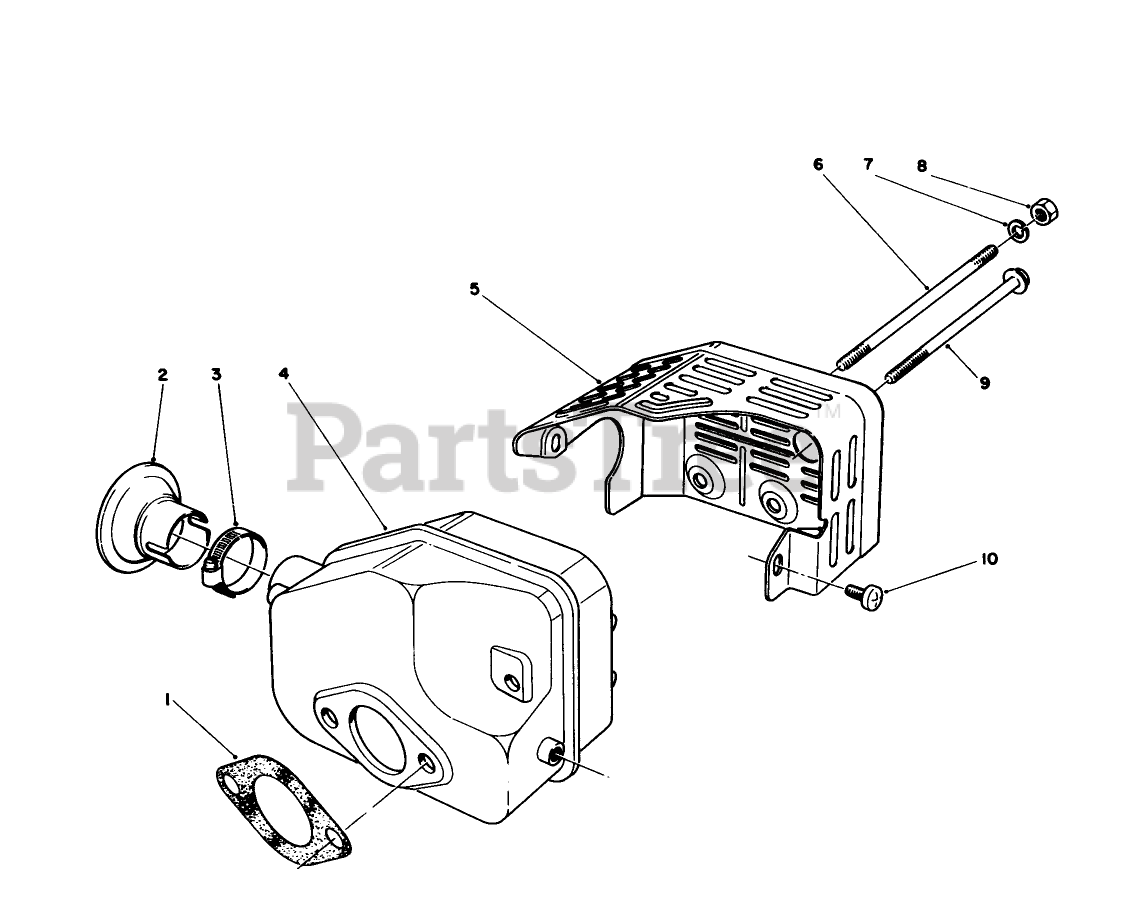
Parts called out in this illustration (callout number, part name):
1	GASKET
3	Clamp
4	MUFFLER
5	COVER-MUFFLER
7	WASHER-LOCK
10	SCREW
